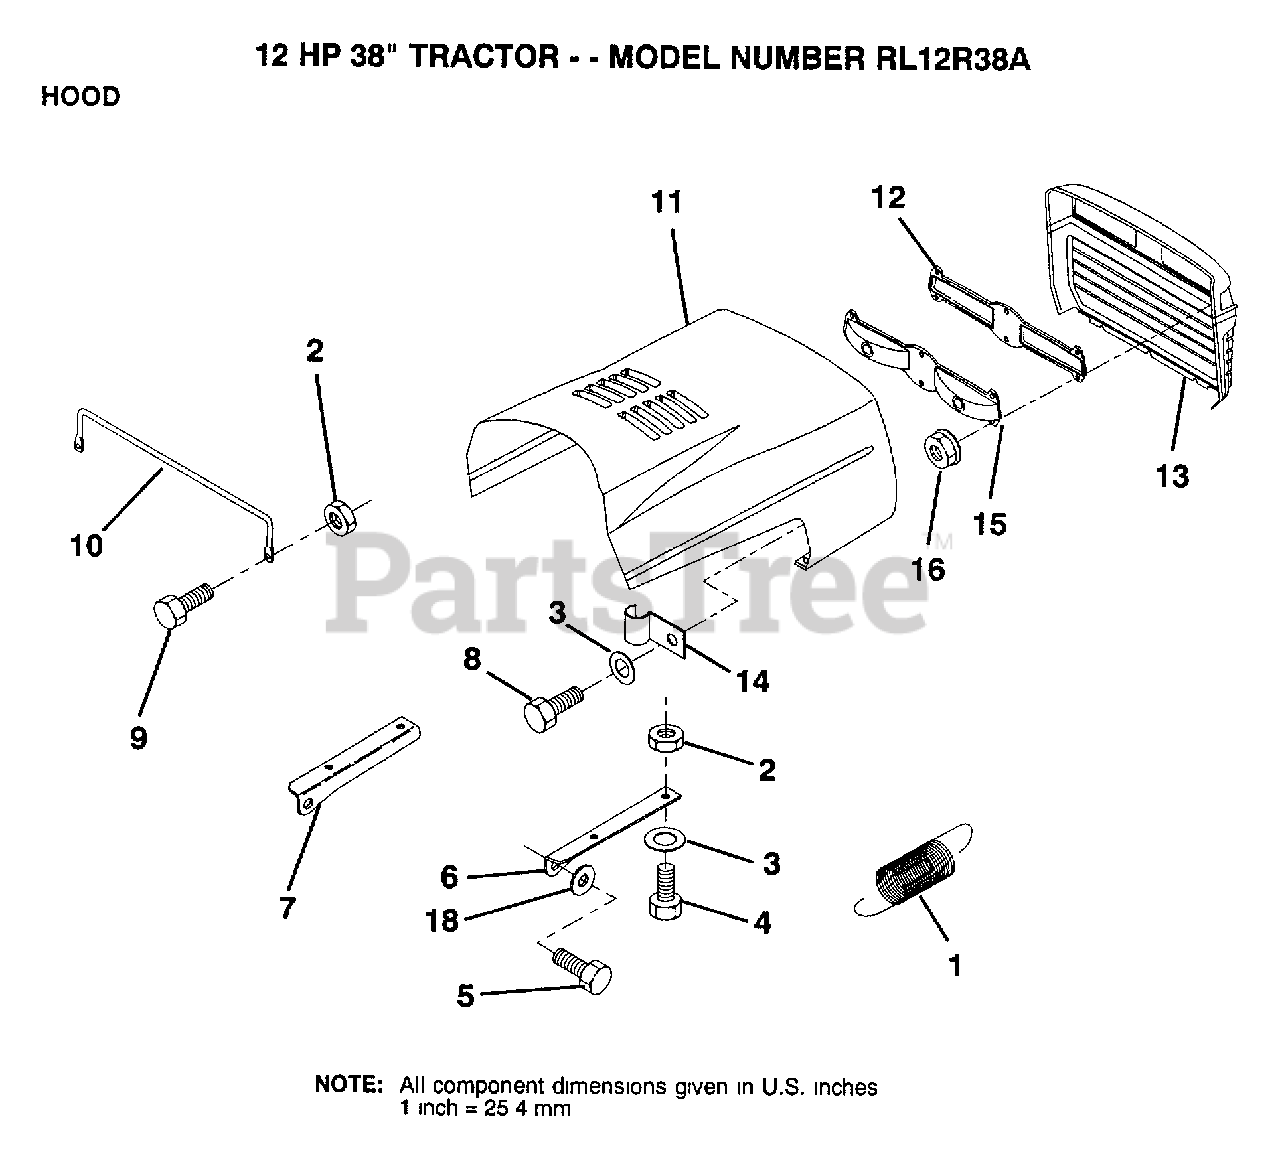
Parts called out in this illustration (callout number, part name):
1	EXT SPRING
2	NUT
3	WASHER
4	BOLT
6	BRKT HOOD RH
7	BRKT HOOD LH
10	"BRACE,HOOD"
11	HOOD
14	CLIP T
16	NUT
18	WASHER
